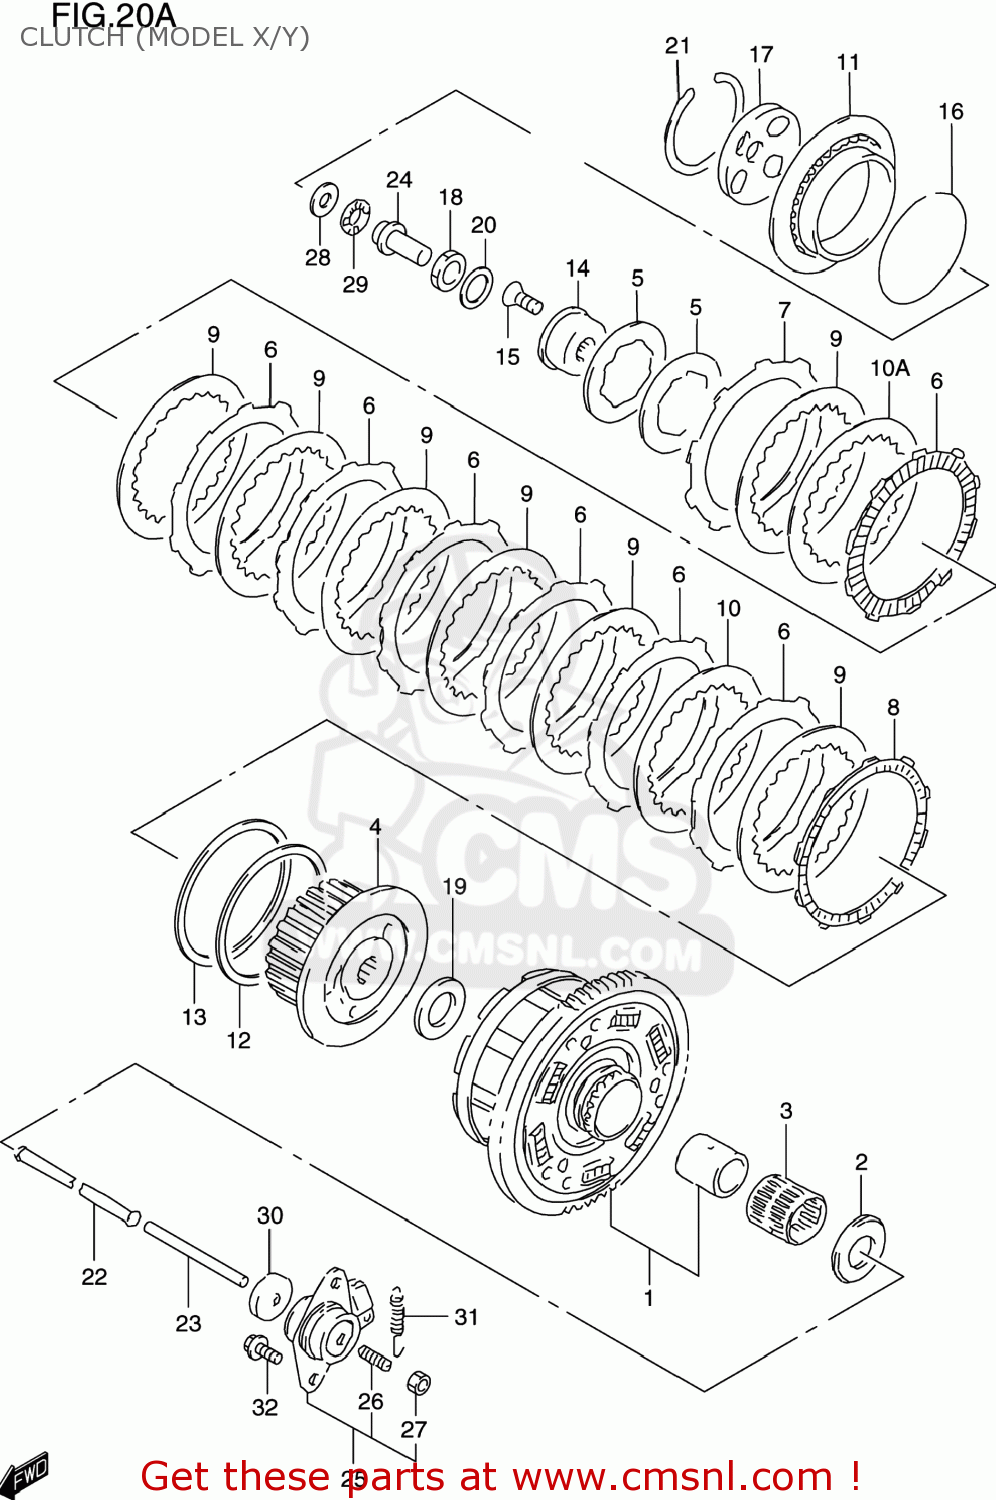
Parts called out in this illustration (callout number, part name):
1	GEAR ASSY,PRI DRIVEN
2	WASHER(25X54X2.5)
3	BEARING(35X40X35.8)
4	HUB,CLUTCH SLEEVE
5	SPRING,CLUTCH
6	PLATE,CLUTCH DRIVE NO.1 (NAS)
7	PLATE,CLUTCH DRIVE (NAS)
8	PLATE,CLUTCH DRIVE NO (NAS)
9	PLATE,CLUTCH DRIVEN NO.1 (NAS)
10	PLATE,CLUTCH DRIVEN NO.2 (NAS)
10A	PLATE,CLUTCH DRIVEN NO.2
11	DISC,CLUTCH PRESSURE
12	SEAT,CLUTCH PLATE WAVE WASHER
13	WASHER,CLUTCH PLATE WAVE
14	HOLDER,CLUTCH SPRING
15	SCREW,CLUTCH SPRING HOLDER
16	SEAT,CLUTCH SPRING
17	LIFTER,CLUTCH PRESSURE DISC
18	NUT
19	WASHER
20	WASHER
21	CIRCLIP
22	ROD,CLUTCH
23	ROD,CLUTCH PUSH,L
24	PIECE,CLUTCH PUSH
25	SCREW ASSY,CLUTCH RELEASE
26	SCREW(6X25)
27	NUT
28	WASHER(15.5X28X1)
29	BEARING(15X28X2)
30	SEAL,OIL(6X34X5.5)
31	SPRING
32	BOLT
